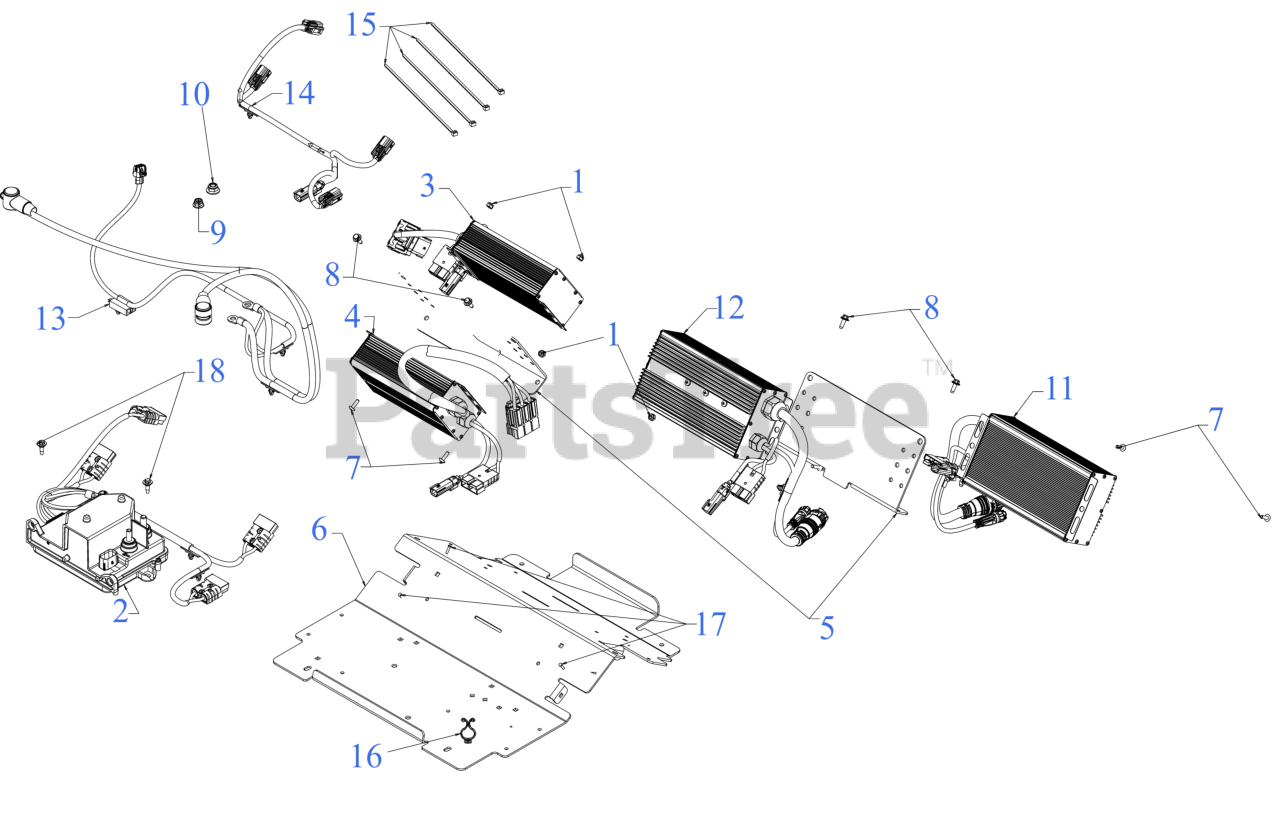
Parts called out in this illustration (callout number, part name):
2	PDM HOUSING (4FUSE)
3	MOTOR CONTROLLER (L-TRAC)
4	MOTOR CONTROLLER (R-TRAC)
5	CONTROLLER BRACKET
6	CONTROLLER PLATE
7	SCREW #10-24 x .62
8	SCREW M6-1 x .625
9	FLANGE LOCK NUT 5/16-18
11	MOTOR CONTROL (L DECK)
12	MOTOR CONTROL (R DECK)
15	TIE CABLE 8.5 LG
16	TWIST LOCK CLIP
17	PANEL RATCHET CLIP .125 x .750
18	SHOULDER SCREW M6-1 .368 X.115
